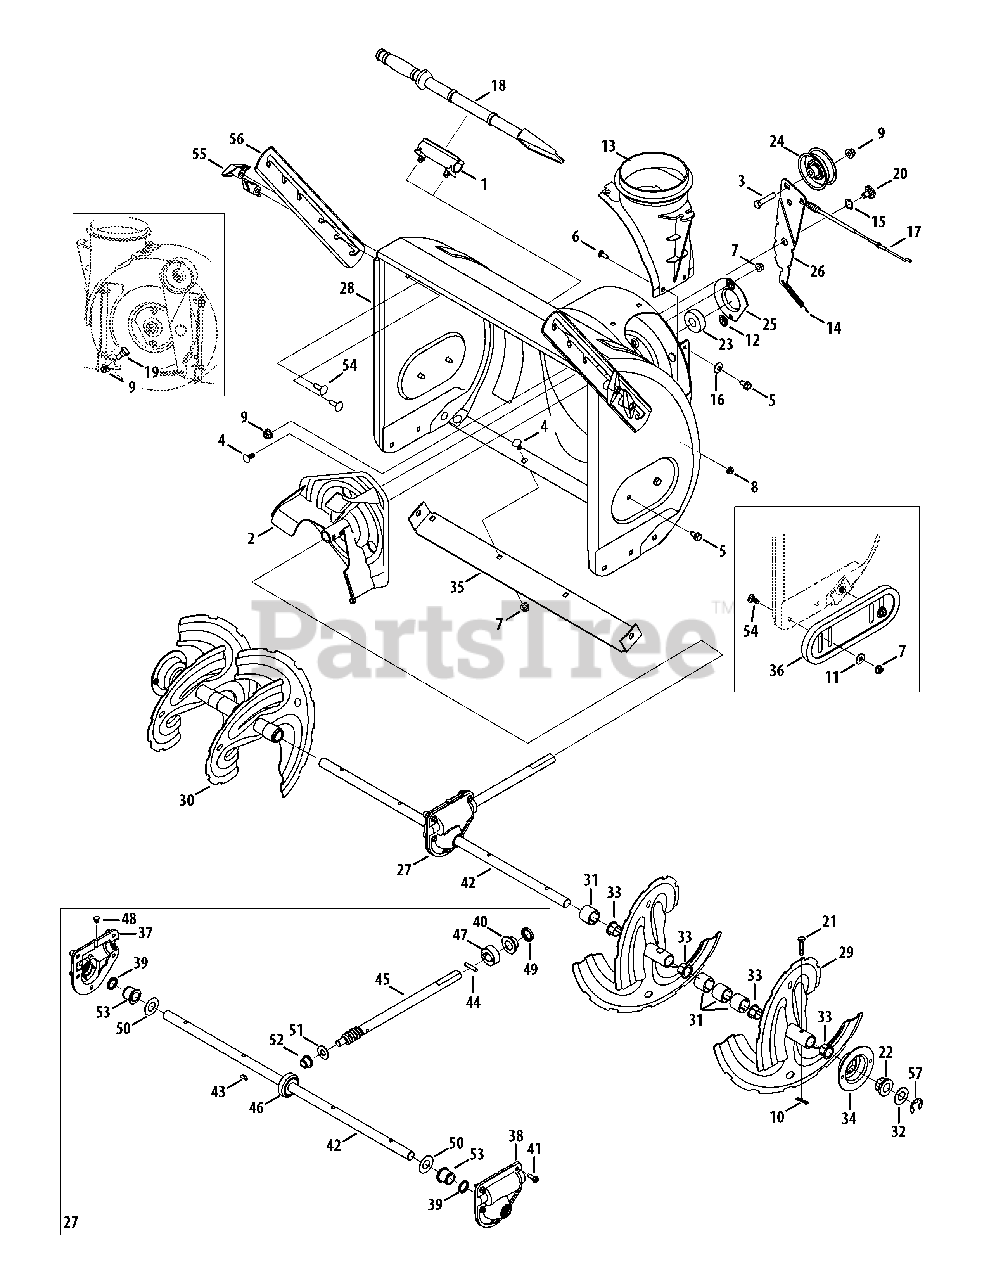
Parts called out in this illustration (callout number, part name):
1	Snow Removal Tool Mount
2	Impeller Assembly, 12" Dia.
3	Hex Screw, 3/8-16, 1.75, Gr5
4	Bolt, Carriage, 5/16-18, .750 Gr1
5	Screw, 5/16-18, 0.750
6	Screw, Carriage, 1/4-20, .750, Gr5
7	Nut, Flange Lock, 5/16-18, Nylon
8	Nut, Flange Lock, 1/4-20, Nylon
9	Nut, Flange Lock, 3/8-16, Nylon
10	Cotter Pin, Bow-tie
11	Washer, Flat, .349 x .879 x .063
12	Nut, Push-on, .25 Dia
13	Chute, Adapter 5" Dia
14	Spring, Extension, .38 OD x 4.59
15	Washer, Wave, .625 x .885 x .015
16	Washer, Bell, .340 x .872 x .060
17	Clutch Cable, Auger, 47.23"
18	Snow Removal Tool
19	Screw, Shoulder, .498 x .34, 3/8-16
20	Screw, Shoulder, .625 x .17, 3/8-16
21	Shear Pin, .25 x 1.50
22	Bearing, Hex Flange x .75 ID
23	Bearing, Ball, .75 ID x 1.85 OD
24	Flat Pulley, Idler, 2.75 OD
25	Housing, Bearing, 1.85 ID
26	Bracket, Auger Idler w/ Brake
27	Gearbox Assembly, Auger, 28"
28	Housing Assembly, Auger 28"
29	Spiral Assembly, LH
30	Spiral Assembly, RH
31	Spacer, 1.25 OD x .75 ID x 1.00
32	Washer, Flat, .76 x 1.49 x .06
33	Bushing, Flange, .80 ID x .91 OD
35	Shave Plate, 2.25 x 27.66
36	Slide Shoe
37	Housing, Auger, RH Reduced
38	Housing, Auger, LH Reduced
39	Seal, Oil, .750 x 1.00 x .125
40	Bearing, Flange, .75 x 1.0 x .59
41	Screw, Self-tapping, 1/4-20, 0.750
42	Axle, Auger, 28"
43	Key, Hi-pro 3/16 x 5/8
44	Pin, Dowel, .25 OD x 1.2
45	Shaft, Worm .75 OD
46	Gear, Worm 20T
47	Collar, Thrust
48	Plug, 1/4 x .437
49	Seal, Oil, .75 x 1 x .131
50	Washer, Flat, .760 ID x 1.5 OD
51	Washer, Flat, .51 x 1.12
52	Bearing, Flange, .75 x 1.0 x .925
53	Bearing, Flange, .75 x 1.00 x .975
54	Screw, Carriage, 5/16-18 x 1.00
55	Wing Knob
56	Drift Cutter
57	E-Ring
